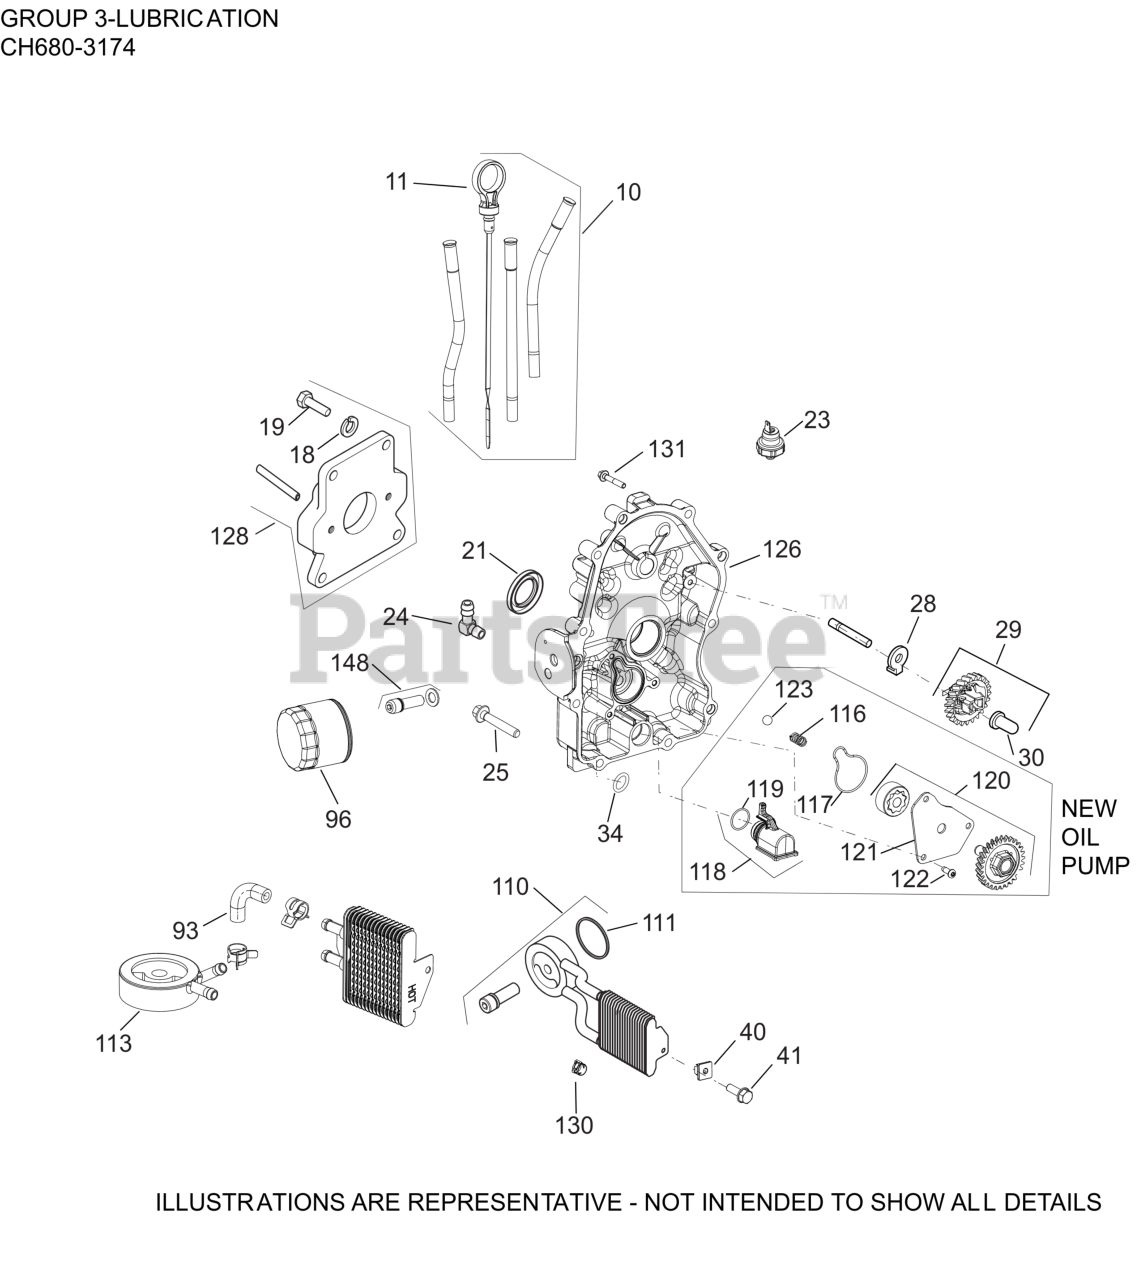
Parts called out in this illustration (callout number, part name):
10	KIT, DIPSTICK/DIPSTICK TUBES
18	WASHER, SPRING LOCK 7/16"
19	SCREW,CAP HD 7/16-14x1 1/2"
23	SENSOR, OIL PSI
24	CONNECTOR, 90 DEG. HOSE
25	SCREW, FLG M8X1.25X45
28	TAB, LOCKING
29	KIT, GOVERNOR GEAR W/PIN
30	PIN, GOVERNOR REGULATING
40	NUT, PLASTIC - BLACK
41	SCREW, HEX HEAD
93	KIT, HOSE 140MM
96	OIL FILTER
110	COOLER,OIL&DIVERTER ASSY-USE 24 594 69-S
111	O-RING, OIL COOLER
113	ADAPTER,OIL FILTER (CV EFI)-(#DSC)
116	SPRING, COMPRESSION
117	SEAL, OIL PUMP COVER
118	PICK-UP ASSEMBLY, OIL
119	O-RING, OIL PICK-UP
120	PUMP ASSEMBLY, OIL
121	COVER, OIL PUMP
122	SCREW, BUTTON HEAD
123	PRESSURE RELIEF BALL
126	KIT, CLOSURE PLATE ASSY
128	KIT, PUMP ADAPTER
130	CLAMP, HOSE LOW PROFILE
131	SCREW, HEX FLANGE
147	ADAPTER, OIL COOLER ASSY-USE 24 594 69-S
148	KIT, OIL FILTER NIPPLE
149	KIT, OIL COOLER
153	SHAFT, GOVERNOR GEAR
154	WASHER, FLAT
